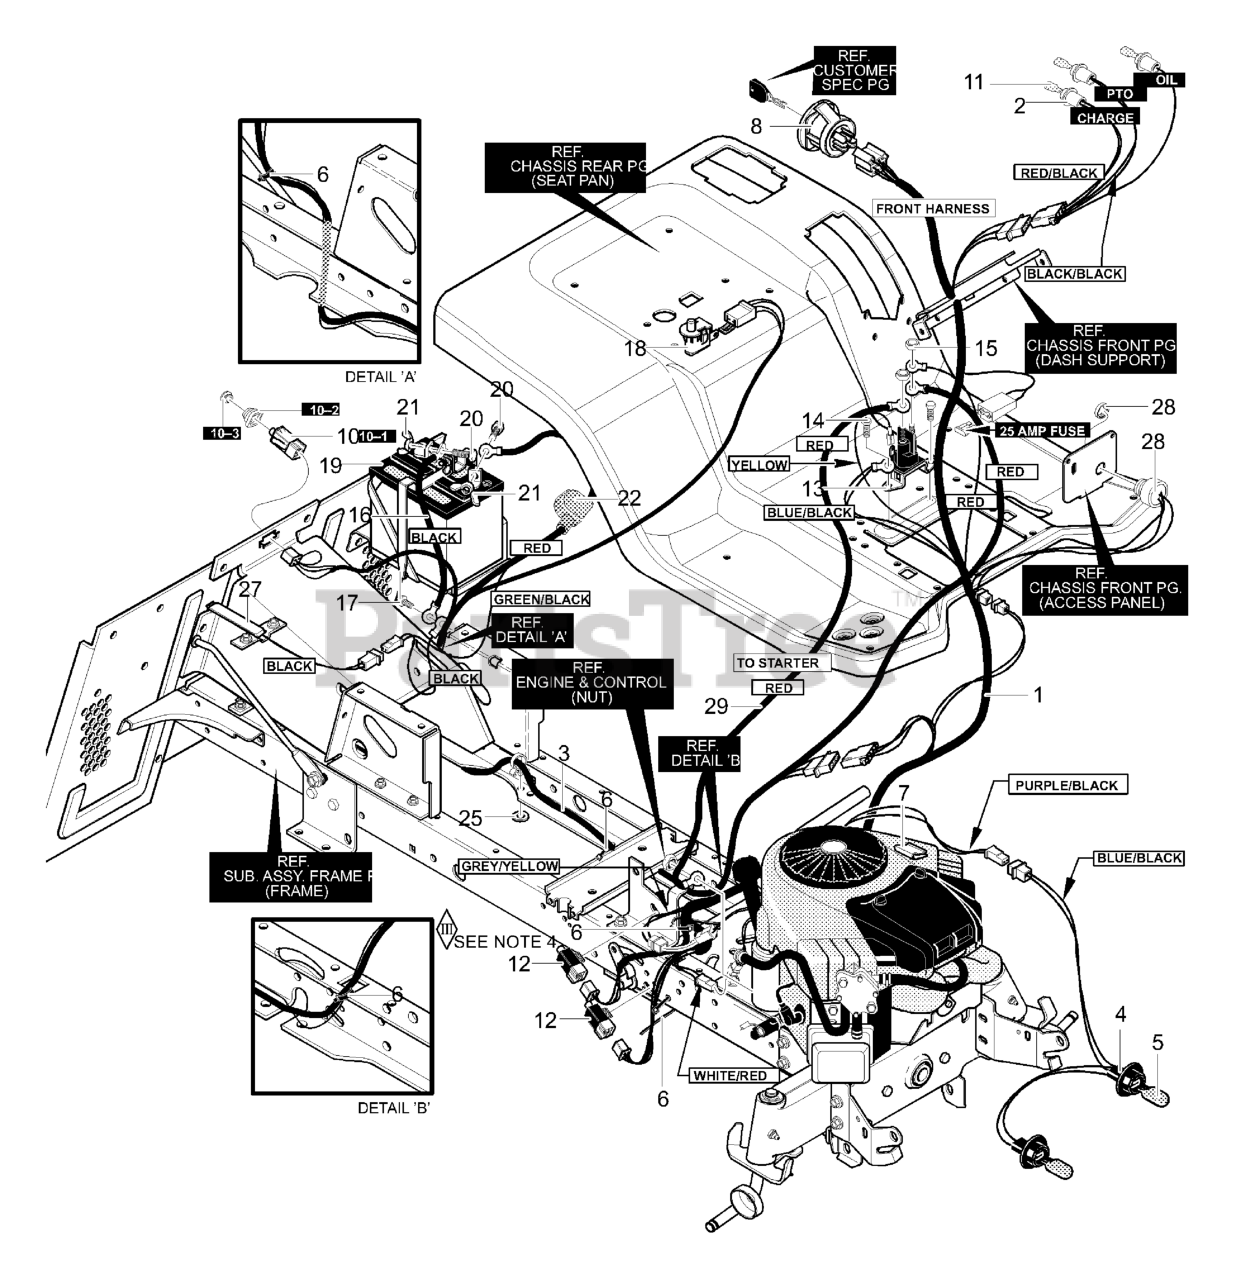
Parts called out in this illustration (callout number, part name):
1	Wire Harness
2	Indicator Harness
3	Rear Harness
4	Wire Harness for Headlights
5	Bulb, Headlamp
6	Cable Tie
7	Wire Clip, Adhesive
8	Switch, Ignition
10	Assy, Switch Double Pole Delta
10-1	Switch, Double
10-2	Boot, Switch
10-3	Switch Cap
11	Bulb, Indicator
12	Switch, Limit
13	Solenoid
14	Screw 1/4x.50
15	Nut, 1/4-20
16	Ground Wire
17	Screw, 1/4x.50
18	Seat Switch
19	Battery 6 Plate
20	Bolt, 1/4-20x.63
21	Wing Nut
22	Battery Boot
25	Flatwasher
27	Tape Switch
28	Buzzer, For Bag Full
29	Wire, Lead Solenoid to Starter
